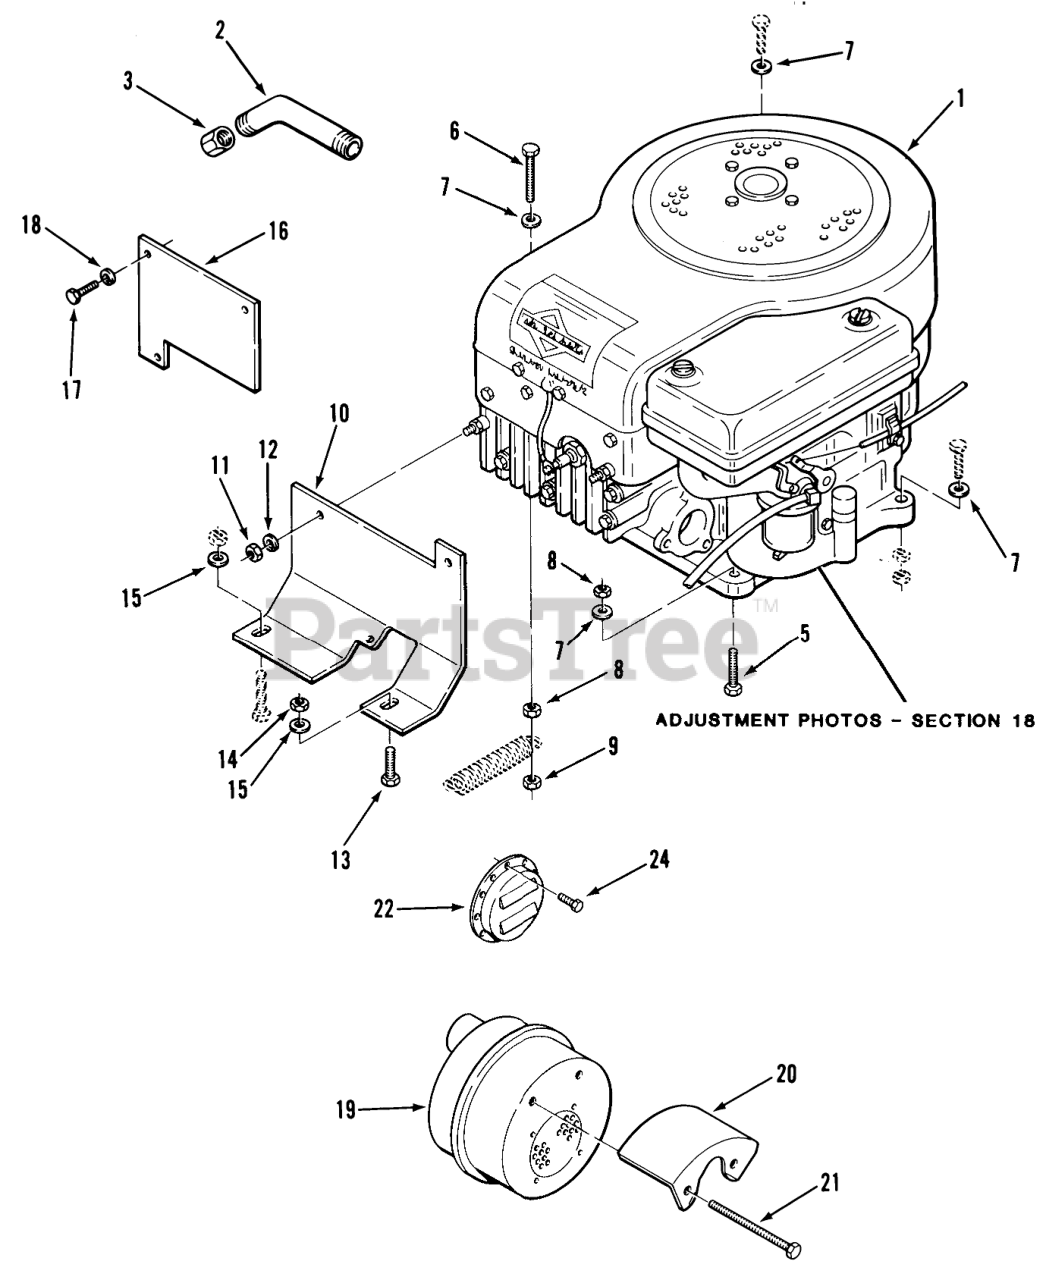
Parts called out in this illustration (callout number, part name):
1	Engine-8 HP B&S Model 190702 Type 2176-01 108-R Only
1	Engine-8 HP B&S Model 193707 Type 0148-01 108-5 Only
1	Engine-11 HP B&S Model 253707 Type 0170-01 111-5 Only
2	Drain Pipe
3	Cap
5	Bolt
6	Bolt 5/16-18 x 2
7	WASHER 5/16 SAE
8	Nut
9	Nut
10	BRACKET ENGINE HE R
11	Nut
12	Lockwasher
13	Bolt
14	NUT
15	Washer
16	PLATE SPRING B
17	Bolt
18	Washer
19	Muffler-Chrome-211-A Only
20	Deflector 45 111-5 Only
21	Screw 8-32 x 3/8 111-6
22	Louvered Deflector
